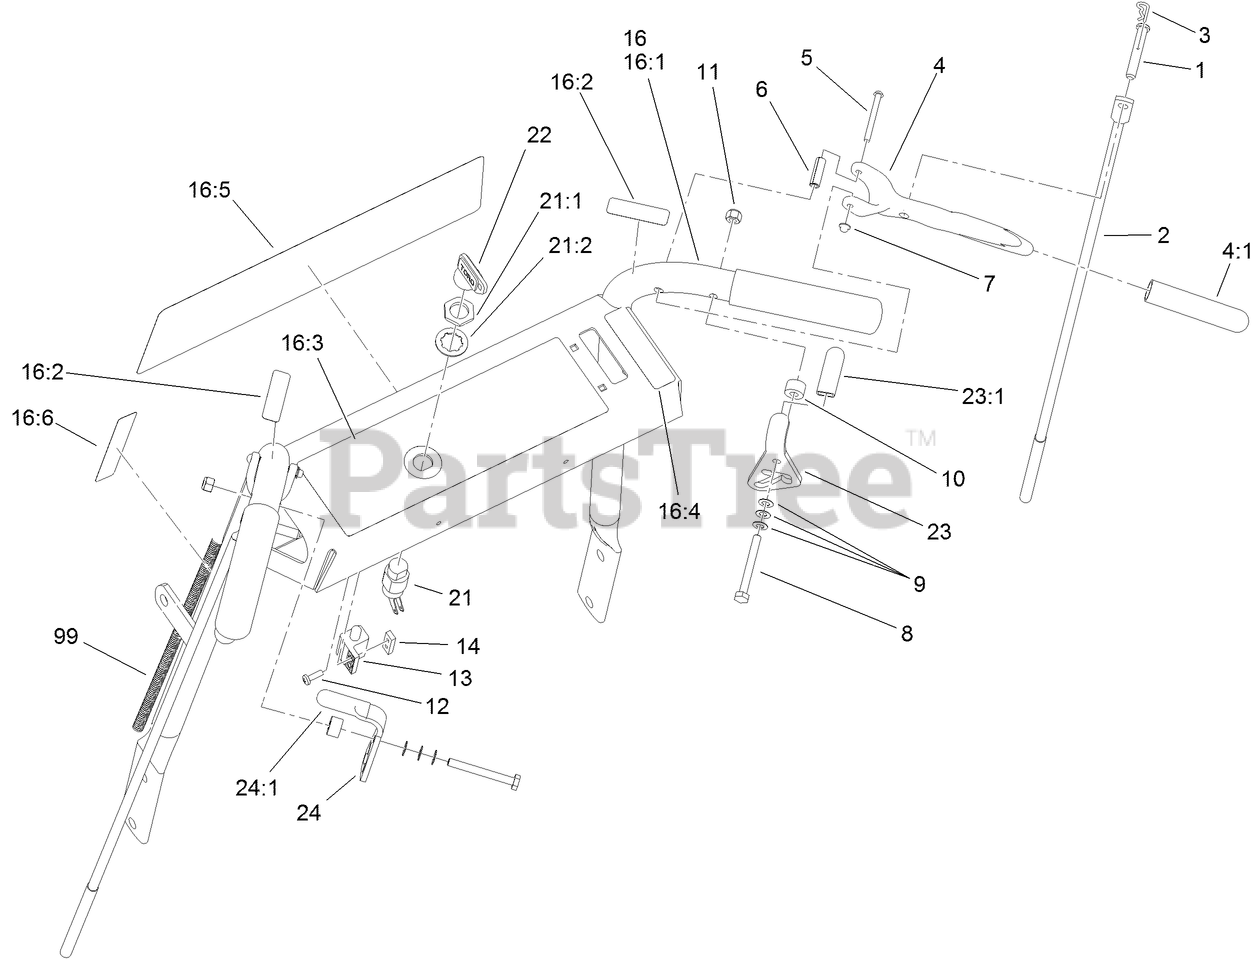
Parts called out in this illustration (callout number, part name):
1	PIN-CLEVIS
2	Linkage-Wheel, Drive
3	PIN-COTTER
4	DRIVE LEVER ASM
4:1	GRIP-LEVER, DRIVE
5	PIN-LEVER, DRIVE
6	PIN-ROLL
8	SCREW-HH
9	WASHER-SPRING
10	SPACER
11	NUT-LOCK, NI
12	SCREW-PPH
13	SWITCH-OPEN, NORMALLY
14	PLATE-TAPPED
16	HANDLE ASM
16:1	PISTOL GRIP HANDLE ASM
16:2	DECAL-LOCK, NEUTRAL
16:3	DECAL-WARNING
16:4	DECAL-THROTTLE
16:6	DECAL-ENGAGE, DECK
21	SWITCH-ON / OFF
21:1	NUT-HH
21:2	WASHER-TOOTH, INTERNAL
22	KEY-IGNITION
23	RH THUMB LATCH ASM
23:1	GRIP-LATCH
24	LH THUMB LATCH ASM
24:1	GRIP-LATCH
99	HARNESS-WIRE
